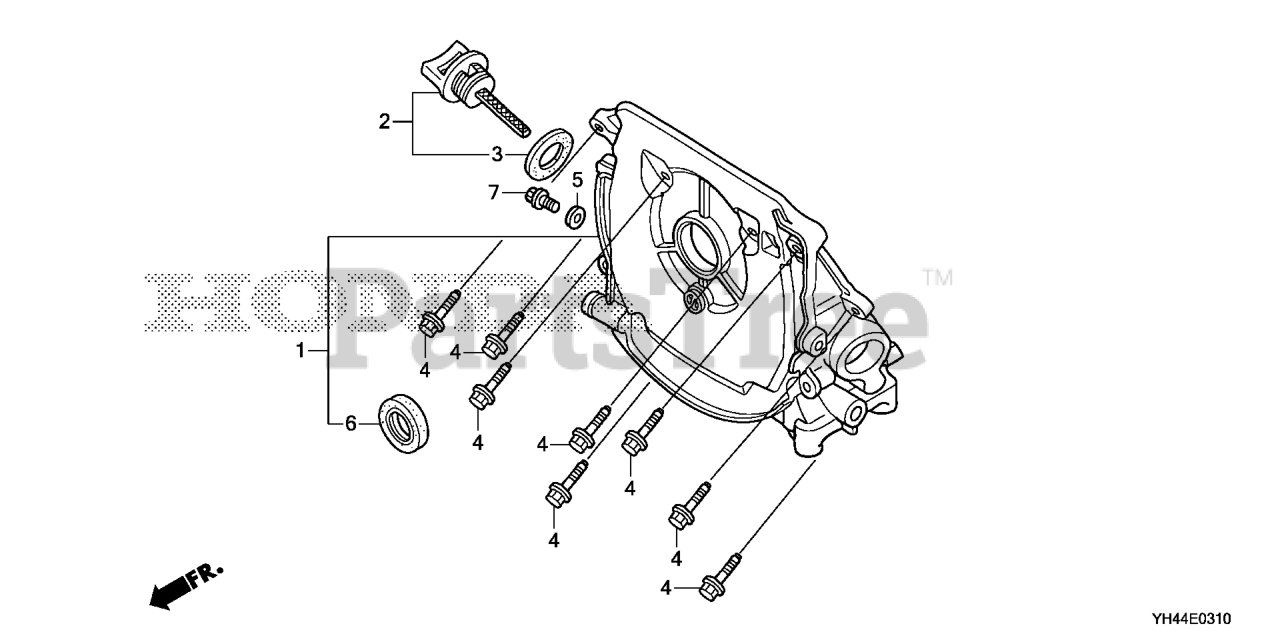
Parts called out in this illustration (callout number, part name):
1	CASE ASSY., OIL
2	CAP ASSY., OIL FILLER
3	GASKET, OIL FILLER CAP
4	BOLT, FLANGE (5X23)
5	GASKET (8MM)
6	OIL SEAL (17X27X5) (KOYO)
7	BOLT, FLANGE (8X12)
